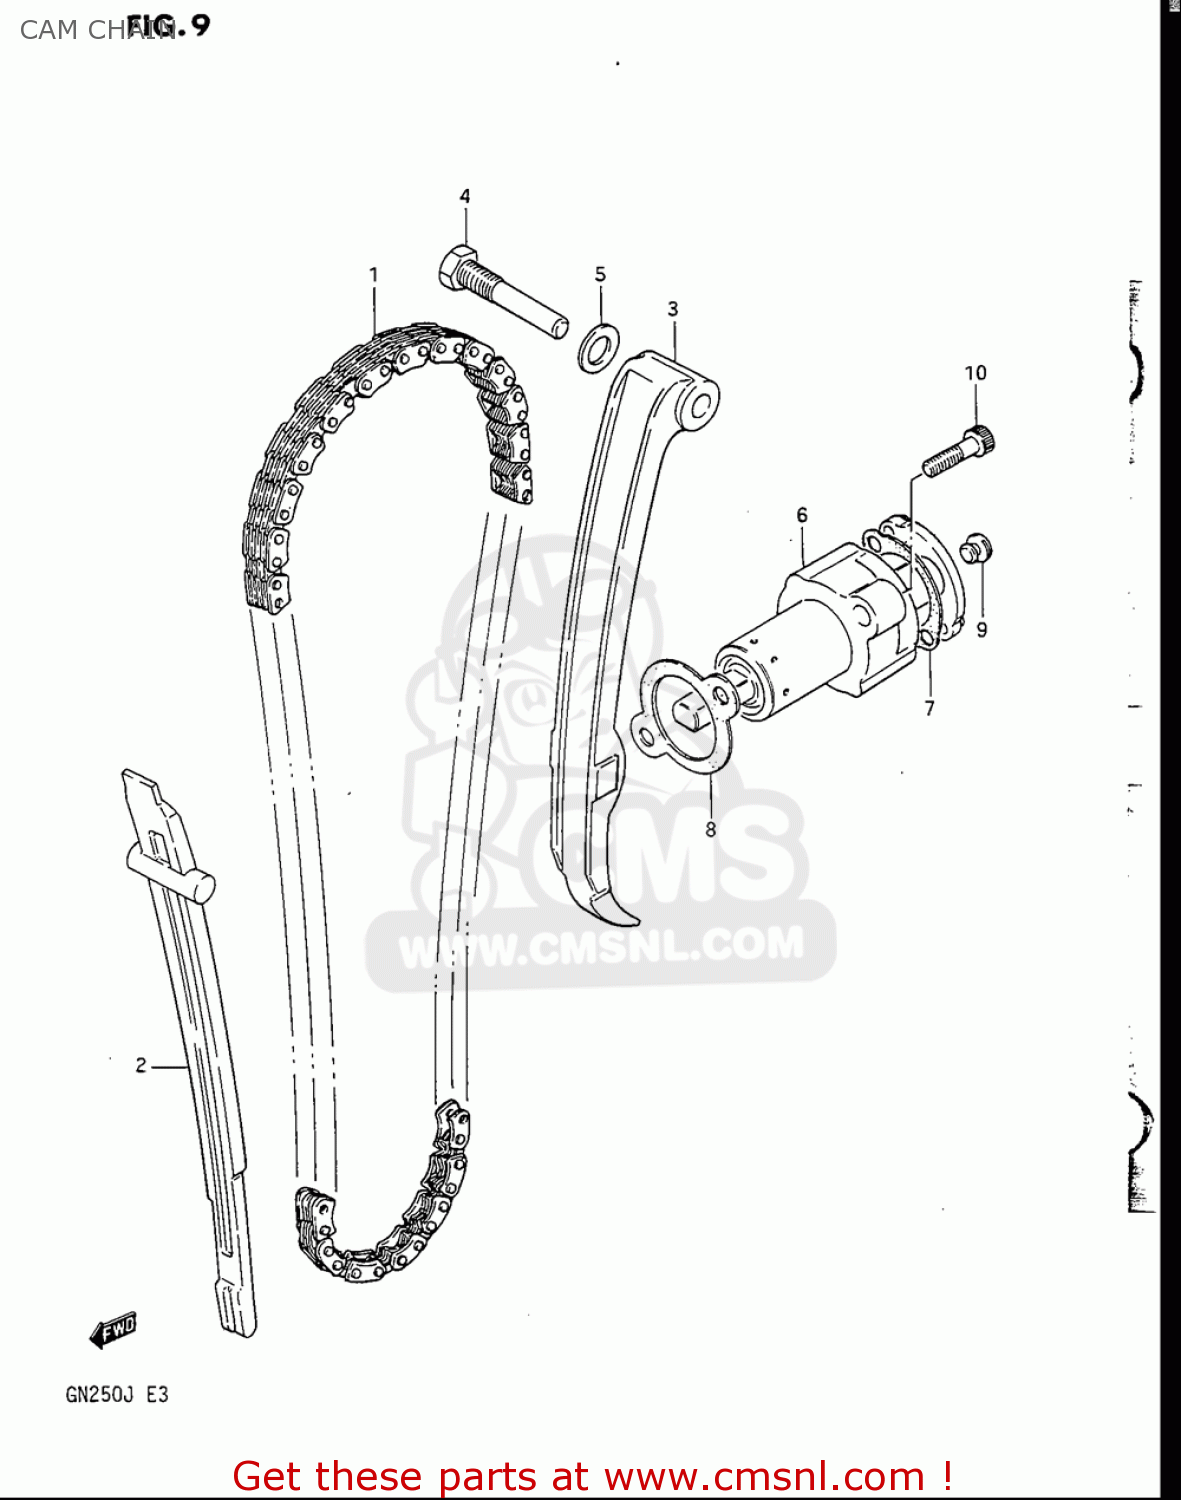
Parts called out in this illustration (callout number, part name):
1	CHAIN,CAMSHAFT DRIVE
2	GUIDE,CAM CHAIN
3	TENSIONER,CAM CHAIN
4	BOLT,CAM CHAIN TENSIONER
5	GASKET(8.2X14X1) (NAS)
6	ADJUSTER ASSY,TENSIONER
7	GASKET,ADJUSTER CAP (NAS)
8	GASKET,TENSIONER ADJUSTER (NAS)
9	PLUG,ADJUSTER
10	BOLT
